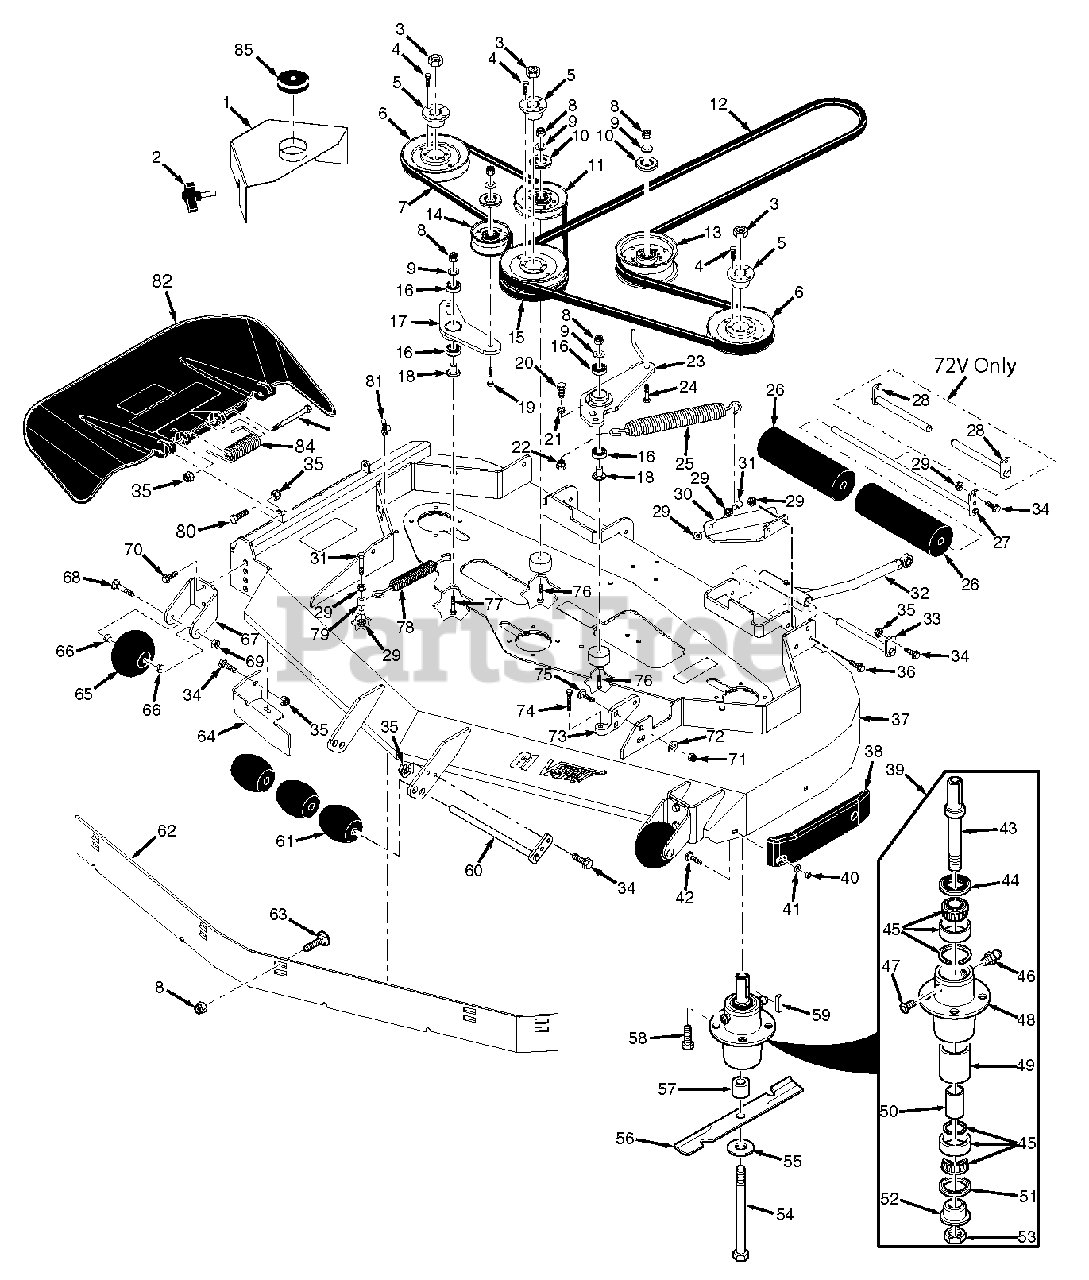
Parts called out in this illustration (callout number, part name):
1	Belt Cover, 61V
1	Belt Cover, 72V
2	Knob w/Stud
3	Nut, 5/8-11 UNC
4	Bolt, Hex Head 1/4-20 x 1"
5	Tapered Hub, 1.125" Bore
6	Pulley, 6.32" Dia.
6	Pulley, 7.50" Dia.
8	Nut, Elastic Stop 3/8-16
9	Flatwasher, 3/8-.391 x .938 x .105
10	Dust Shield
11	Pulley, Idler
12	Belt, Deck Drive
13	Pulley, 5" Idler
14	Pulley, 3-1/2" Idler
15	Pulley, 6.32" Dia. Double Groove
15	Pulley, 7.50" Dia. Double Groove
16	Bearing
17	Idler Arm Assy.
18	Pivot, Idler
19	Bolt, Hex Head 3/8-16 x 2-1/2"
20	Bolt, Hex Head 7/16-14 x 1"
21	Lockwasher, 7/16" Spring
22	Boss, Spring Anchor
23	Idler Arm Assy.
24	Bolt, Hex Head 3/8-16 x 3"
25	Spring, LH Cutter Deck
26	Guide Roller
27	Shaft Weldment
28	Shaft Weldment
29	Nut, Serrated Flange 3/8-16
30	Spring Mount, SCZ
31	Bolt, Hex Head 3/8-16 x 1-1/2"
32	Pusharm Assy., LH
32	Pusharm Assy., RH
33	Rod Weldment, Pusharm
34	Bolt, Hex Head 5/16-18 x 1"
35	Nut, Elastic Stop 5/16-18
36	Bolt, Hex Head 3/8-16 x 1"
37	Cutter Deck w/Decals
38	Wear Pad
39	Spindle Assembly
40	Nut, Center Lock 5/16-18
41	Flatwasher, 5/16-.344 x .688 x .065
42	Bolt, Carriage 5/16-18 x 3/4"
43	Shaft, Spindle
44	Seal, Top
45	Bearing Assembly
46	Grease Fitting
47	Relief Fitting, Spindle
48	Spindle Housing
49	Spacer, Outside
50	Spacer, Inside
51	Seal, Bottom
52	Spindle Bushing
53	Nut, Special 1-1/16 - 18
54	Bolt, Hex Head 5/8-11 x 9-1/2"
55	Flatwasher, 5/8-.688 x 1.75 x .134 HD
56	Cutter Blade, 21"
56	Cutter Blade, 24-1/2"
57	Spacer, Spindle Bottom
58	Bolt, Hex Head 5/16-18 x 1-3/4"
59	Key, 1/4 x 1/4 x 2"
60	Shaft Weldment
61	Wheel, Anti-Scalp
62	Baffle, Flange - 61V
62	Baffle, Flange - 72V
63	Bolt, Carriage 3/8-16 x 1"
64	Baffle, Turbo - 61V
64	Baffle, Turbo - 72V
65	Wheel, Anti-Scalp
66	Bushing, .376 ID Oilite
67	Bracket, Anti-Scalp Wheel
68	Bolt, Carriage 3/8-16 x 4"
69	Nut, Center Lock 3/8-16
70	Bolt, Hex Head 3/8-16 x 1" Serrated Flange
71	Nut, Elastic Stop 7/16-14
72	Flatwasher, 1/2-.531 x 1.062 x .095
73	Lever Assembly, Deck Level
74	Bolt, Deck Adjust
75	Bolt, Carriage 7/16-14 x 1-1/4"
76	Bolt, Hex Head 3/8-16 x 3"
77	Bolt, Hex Head 3/8-16 x 2-1/4"
78	Deck Spring
79	Spacer
80	Bolt, Hex Head 5/16-18 x 1-3/4"
81	U-Nut, 3/8-16
82	Discharge Chute Assy. 61V
82	Discharge Chute Assy. 72V
83	Bolt, Hex Head 5/16-18 x 4-1/2"
84	Spring, Discharge Chute
85	Cap, Spindle
